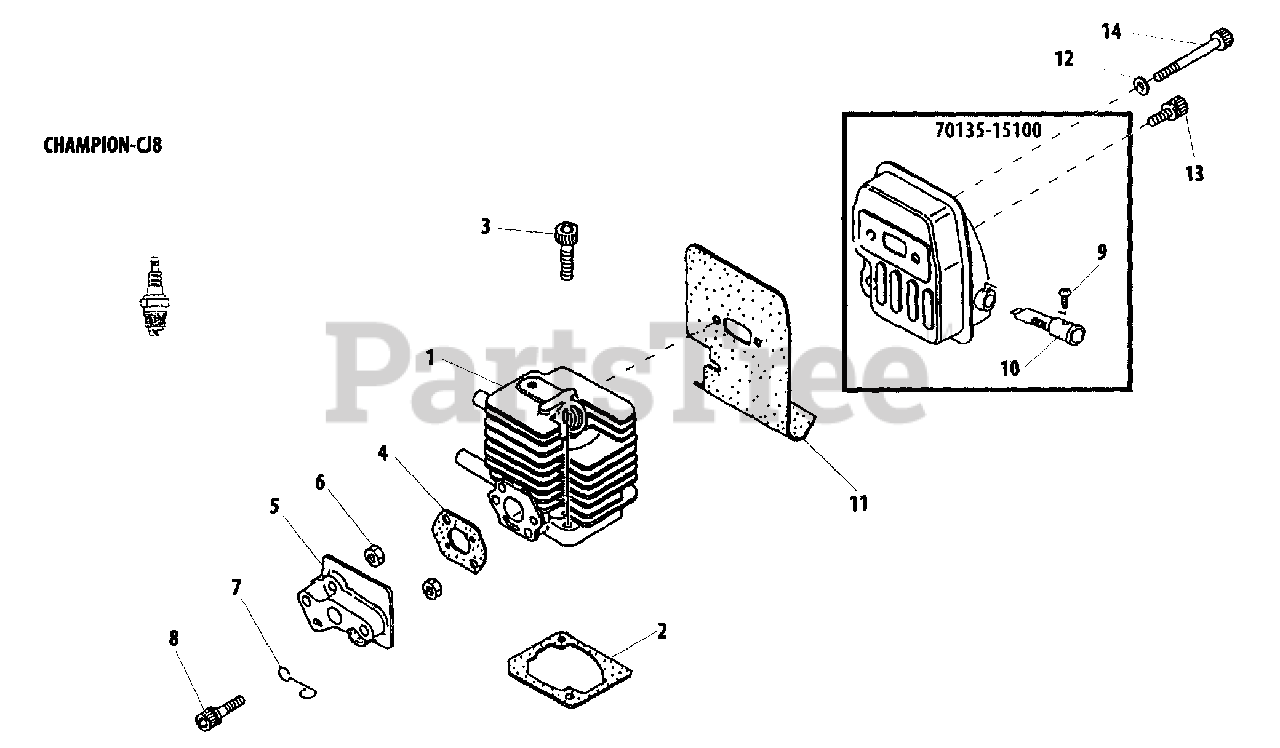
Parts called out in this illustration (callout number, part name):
1	CYLINDER
2	GASKET, CYLINDER
3	BOLT 5×25
4	GASKET, INTAKE
5	INSULATOR
6	NUT M5×6.3
7	CLIP, VENT ASSY
8	BOLT M5×25
9	SCREW, TAPPING 3×6
10	SCREEN, SPARK ARRESTER
11	GASKET, EXHAUST
12	WASHER, FLAT 5.5×10×0.8
13	BOLT 5×12
14	BOLT M5×50
70135-15100	MUFFLER ASSY
